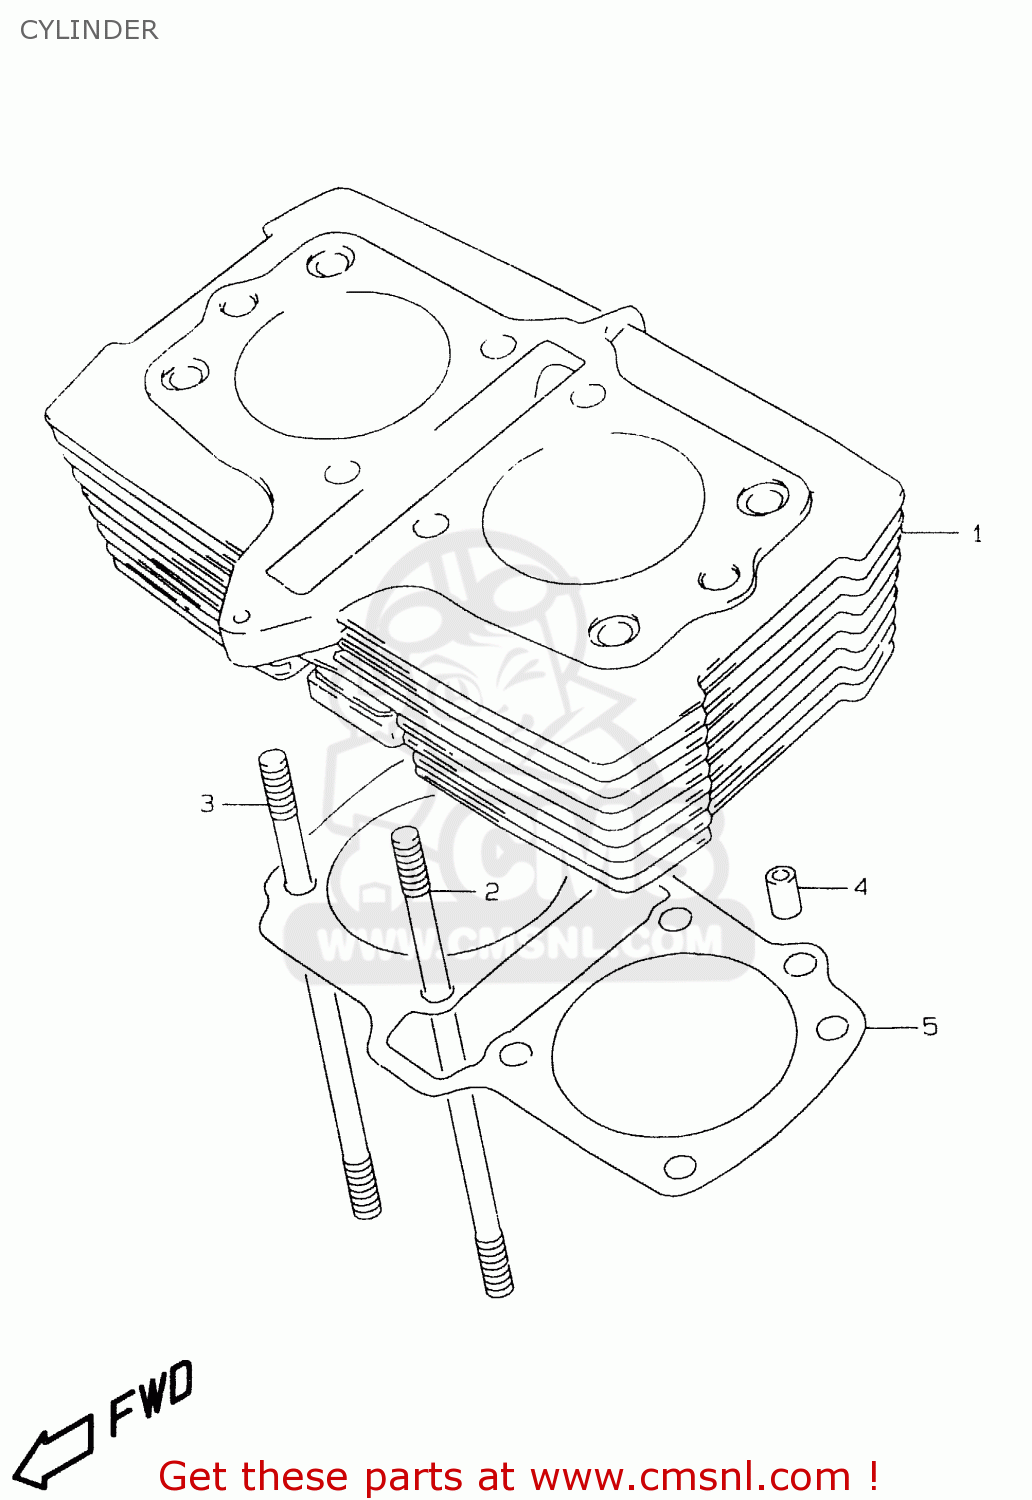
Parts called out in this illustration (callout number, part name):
1	CYLINDER
2	BOLT,STUD
3	BOLT,STUD
4	PIN
5	GASKET,CYLINDER (NAS)
